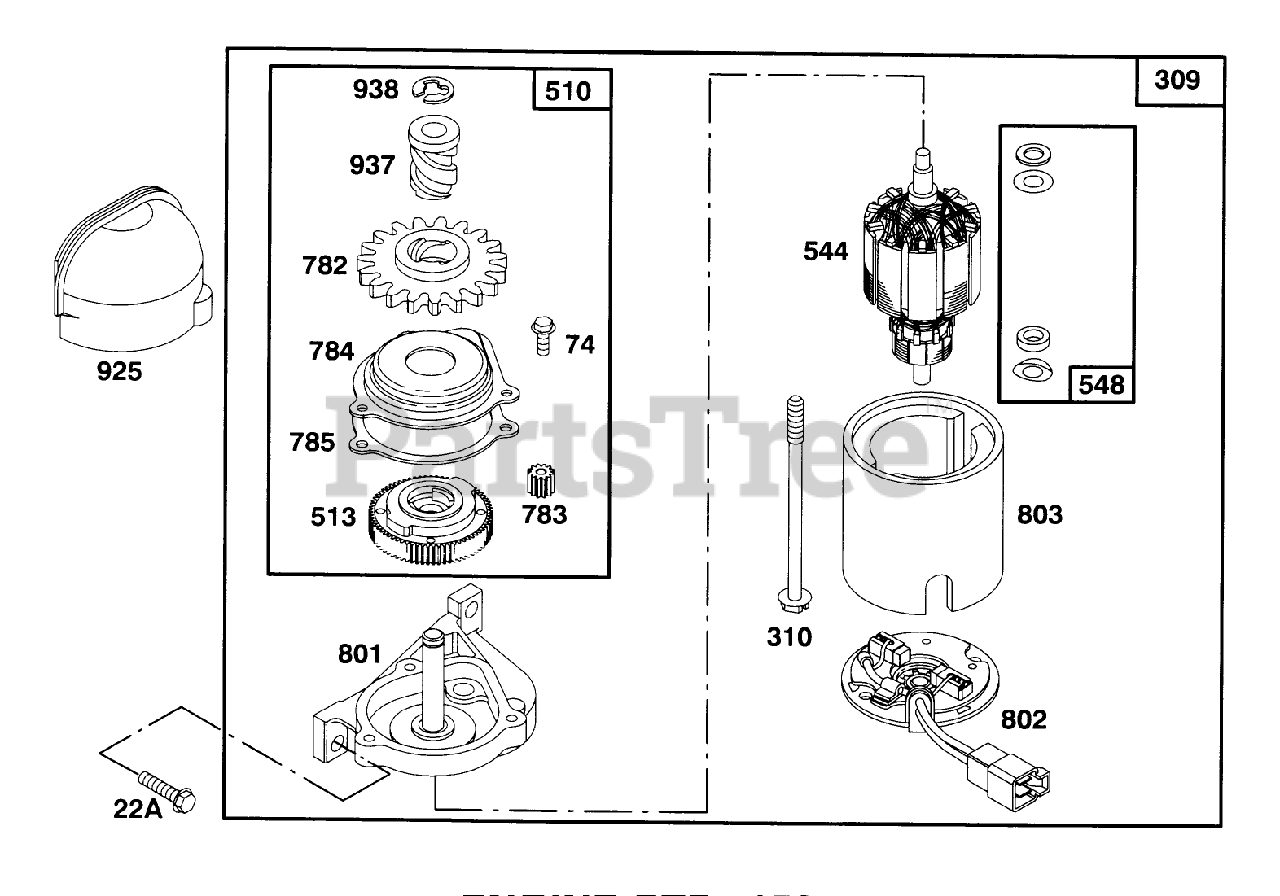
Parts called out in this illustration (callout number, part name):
22A	SCREW - CARBUERTOR MTG
510	DRIVE SET
513	CLUTCH - STARTER
548	WASHER ASSEMBLY
782	GEAR - STARTER
925	COVER - STARTER
938	RETAINER - LOCK
